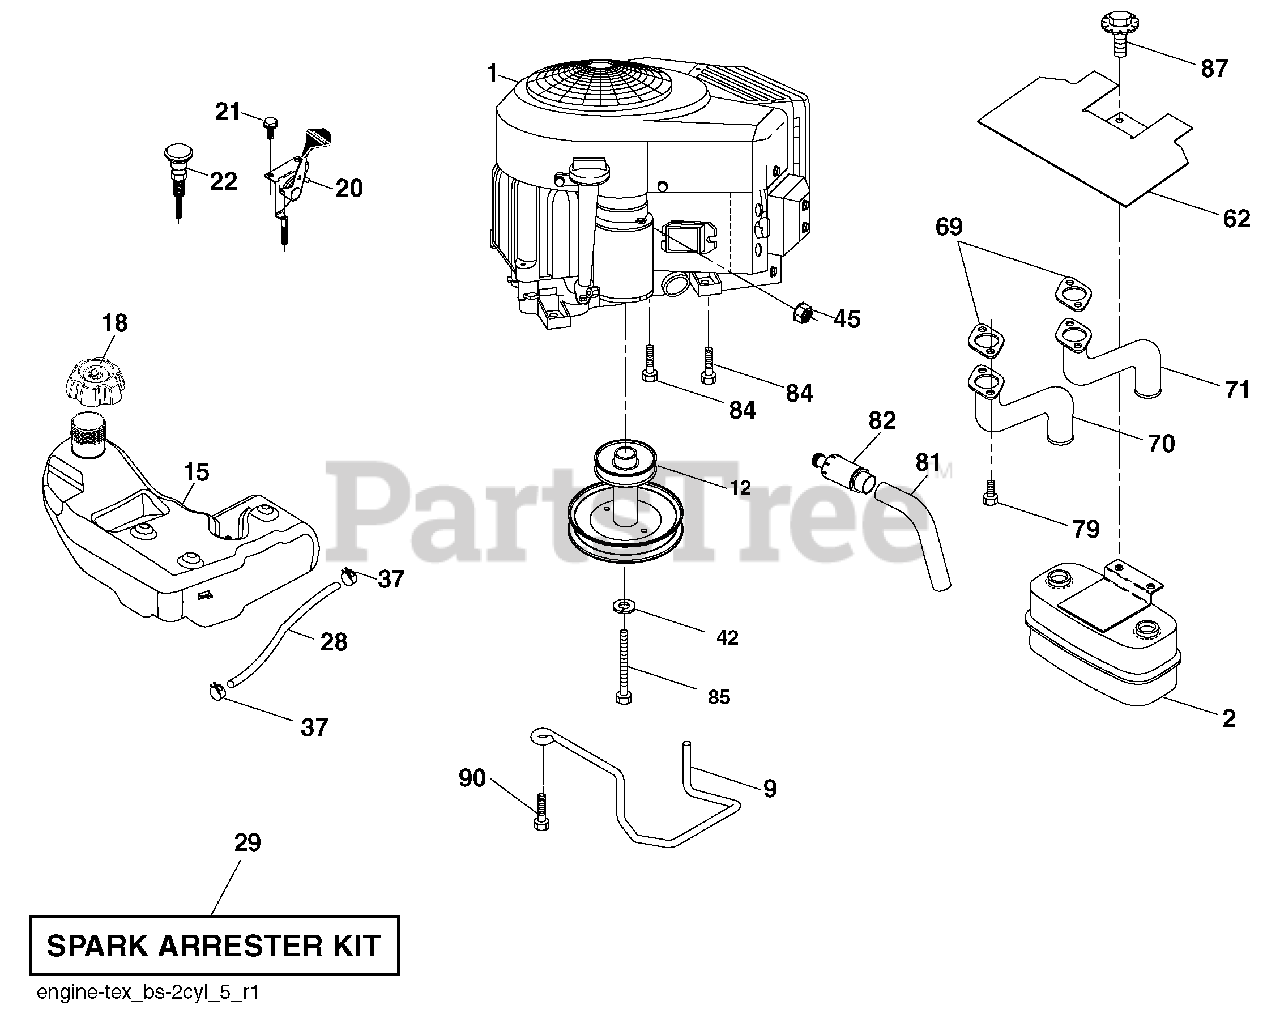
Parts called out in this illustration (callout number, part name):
2	Muffler
9	Keeper Belt Engine
12	Pulley Engine
15	Tank Fuel 3.0
18	Cap Asm
20	Control Throttle
21	Screw #10 x 0.750 BOS Thread
22	Control Choke
28	Fuel Line
29	Spark Arrester Kit
37	Clamp Hose
42	Washer Lock 7/16
45	Nut Keps Hex 1/4-20 unc
62	Shield Heat Muffler
69	Gasket
70	Exhaust Tube RH
71	Exhaust Tube LH
79	Screw Socket Head 5/16-18 x 1
81	Tube Drain Oil Easy
82	Plug Drain Oil
84	Screw 3/8-16 x 1-1/4
85	Bolt Hex 7/16-20 x 4 x 5 Ga.-1.5
87	Bolt 5/16-18 x 3/4
90	Screw 3/8-16 x 1
